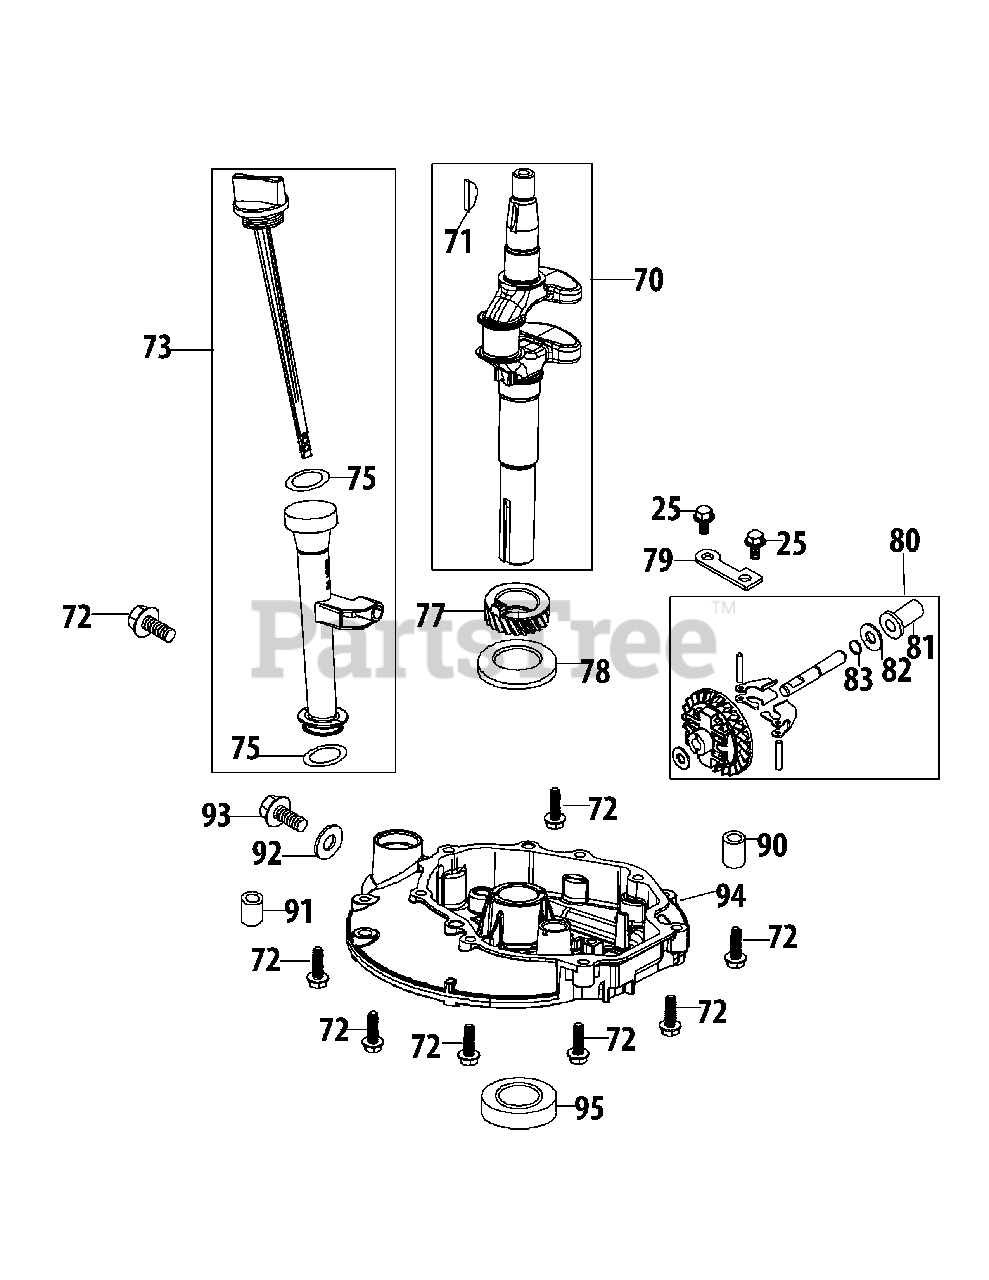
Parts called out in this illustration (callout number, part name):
25	Bolt M6×14 Multi-Purpose
70	Crankshaft Assembly
71	Flywheel Key
72	Bolt M6X28 T/X/P Crankcase/Dp Stick
73	Dipstick Assembly
75	Dipstick / Oil Fill Tube O-Ring
77	Timing Gear
78	Crankshaft Thrust Washer
79	Governor Gear Mounting Plate
80	Governor Gear/Shaft Assembly
81	Governor Slide Cap
82	Governor Slide Cap Washer
83	Governor Shaft Stop Ring
90	Crankcase Cover Dowel Pin 7×14
91	Crankcase Cover Dowel Pin 9×14
92	Oil Drain Plug Washer
93	Oil Drain Plug
94	Crankcase Cover
95	Lower Crankshaft Seal
